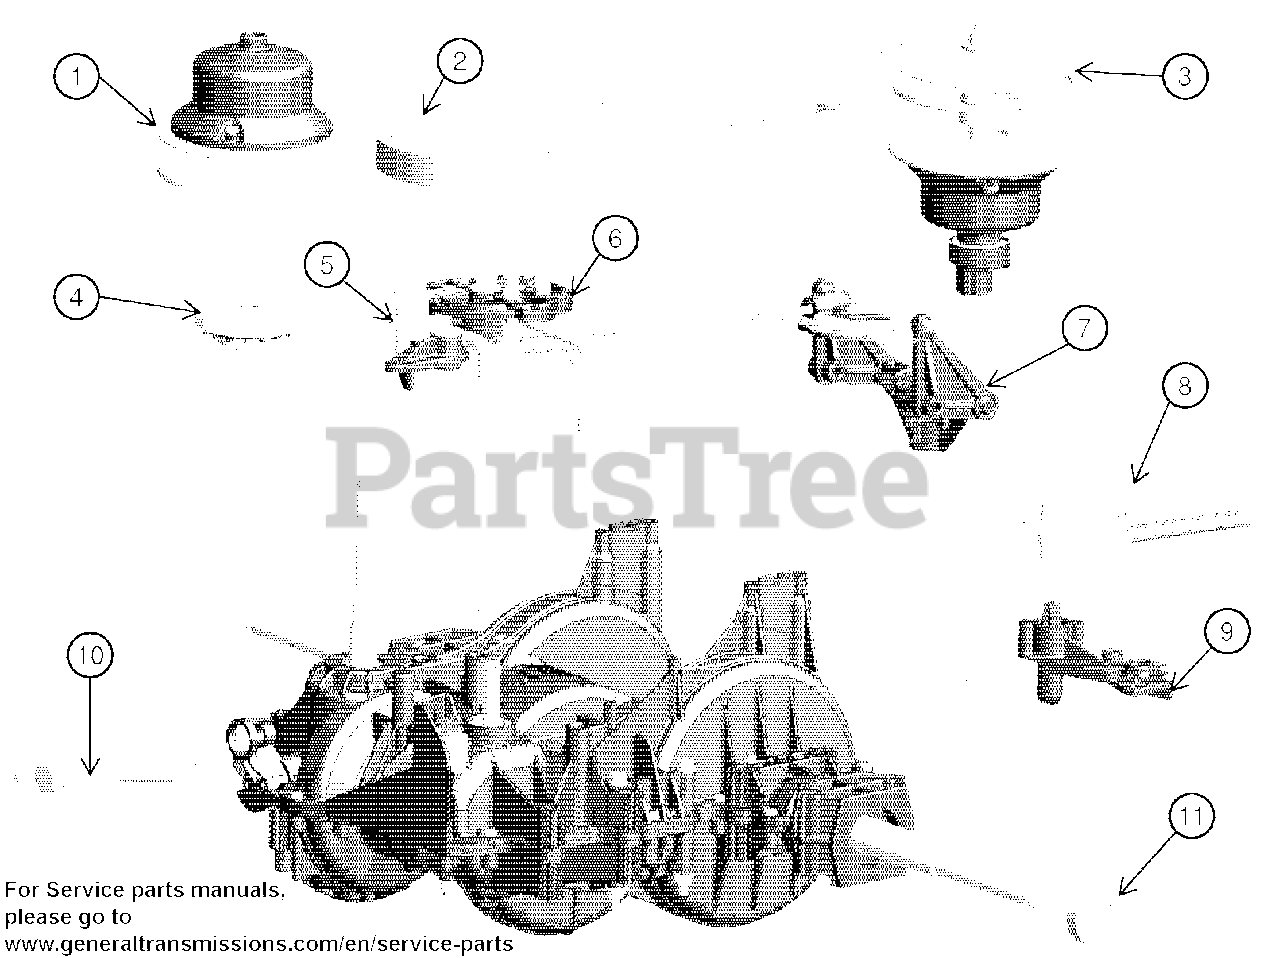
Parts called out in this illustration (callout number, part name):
1	DRIVEN KIT RS800
2	VARIATION BELT
3	DRIVER / ANTI DEBRIS KIT
4	TRANSMISSION KIT
5	CONTROL
7	TRANSMISSION KIT
8	BRAKE KIT
9	BYPASS KIT
10	INVERSION KIT
11	OUTPUT SEAL (QTY 1)
